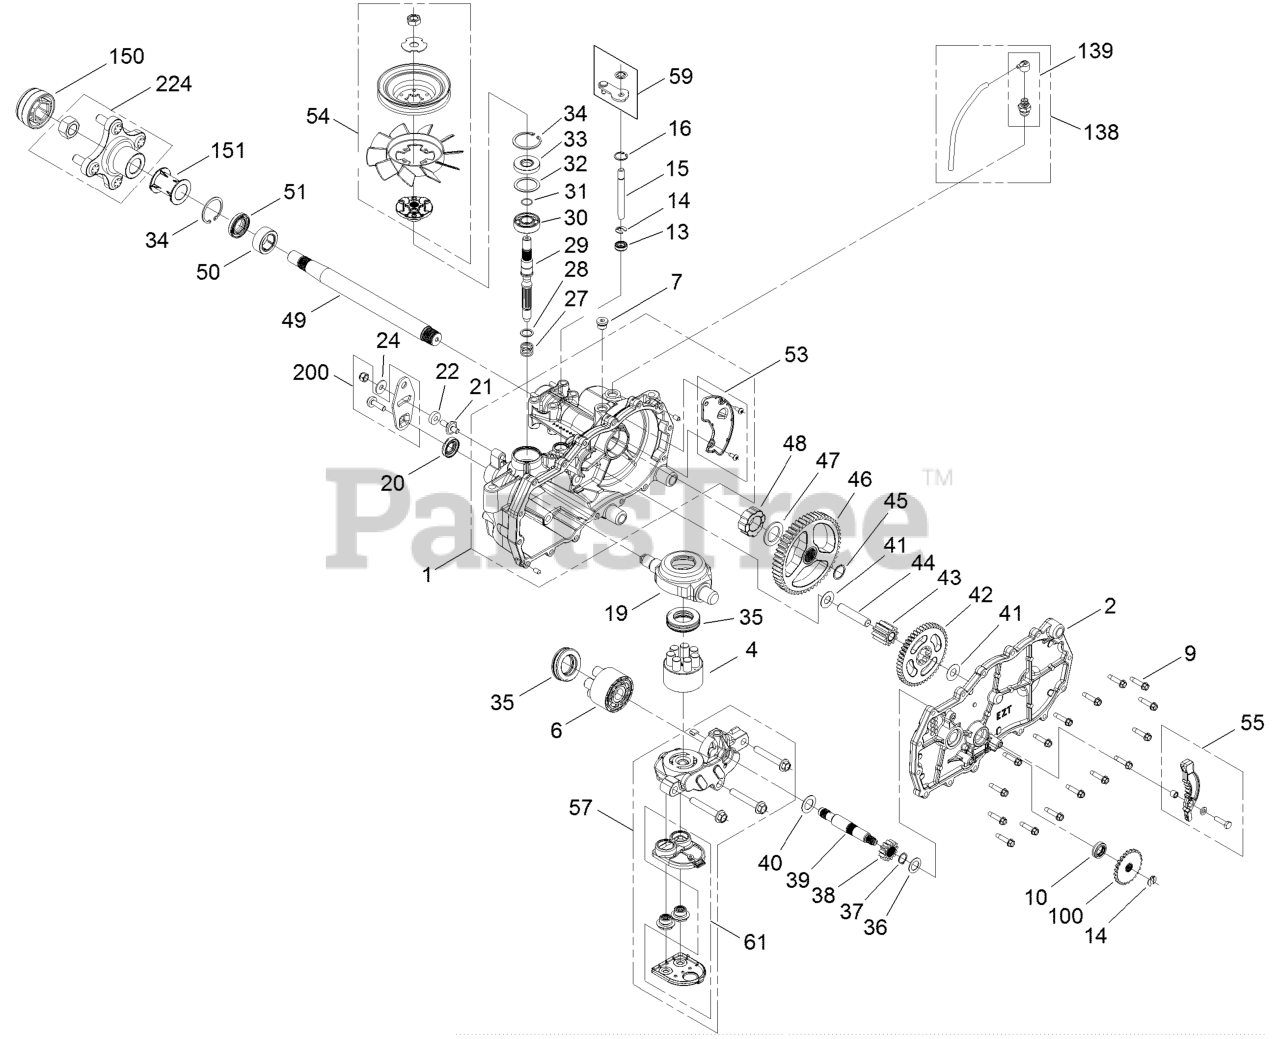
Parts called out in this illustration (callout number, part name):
1	MAIN HOUSING ASM
2	SIDE ASM
4	PUMP BLOCK ASM
6	CYLINDER BLOCK KIT
7	PLUG-THREAD, STRAIGHT
9	SCREW-HHF
10	SEAL-OIL
13	SEAL-LIP
14	RING-RETAINING, EXTERNAL
15	ROD-BYPASS
16	RING-RETAINING, INTERNAL
19	SWASHPLATE-TRUNNION
20	SEAL-LIP
22	PUCK-FRICTION
29	SHAFT-INPUT
30	BEARING-BALL
31	RING-RETAINING
33	SEAL-LIP
34	RING-RETAINING
35	BEARING-THRUST
36	WASHER-FLAT
37	RING-RETAINING
38	GEAR-PINNION, 13T
39	SHAFT-MOTOR
41	Washer
42	GEAR-10T/48T
43	GEAR-JACKSHAFT, 10T
44	PIN-JACKSHAFT
45	RING-SPIRAL, RETAINING
46	GEAR-52T, BULL
48	BEARING-SLEEVE
49	SHAFT-AXLE
50	BUSHING-AXLE
51	SEAL-LIP
53	EXPANSION PLATE KIT
55	BRAKE ARM KIT
57	CENTER SECTION FILTER KIT
59	BYPASS KIT
61	FILTER KIT
100	DISC-BRAKE, COG
138	BREATHER KIT
139	BREATHER ASM
150	COVER-NUT, AXLE
151	TUBE-AXLE
200	CONTROL ARM KIT
